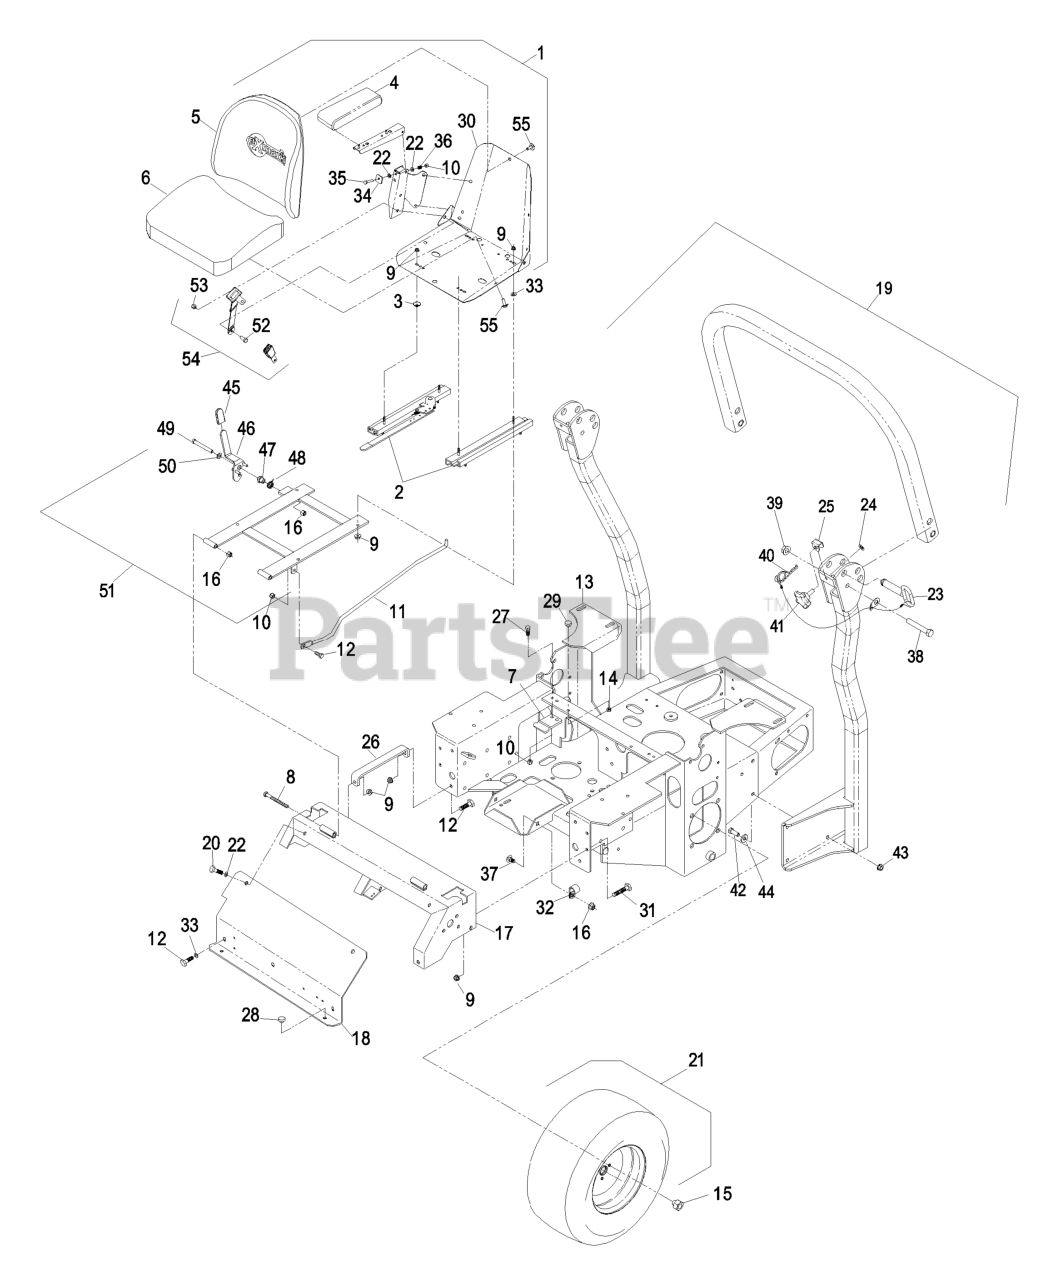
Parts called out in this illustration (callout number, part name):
1	KIT,SEAT W/ARMREST ADJ.
2	TRACK-SEAT
3	SPACER-TRACK
4	CUSHION,ARMREST RH
5	CUSHION,SEAT BACK
6	CUSHION,SEAT BOTTOM
7	CATCH-LATCH, SEAT
8	SCREW-HH
10	NUT-LOCK, NI
11	ROD-RETAINER, SEAT
12	SCREW-HH
15	NUT-LUG
16	NUT-LOCK, NI
17	ASM,CONSOLE WELDMENT W/DE
19	KIT, LAZER HP / CT 2 POST
20	SCREW-HH
21	ASM,WHEEL AND TIRE
22	WASHER-PLAIN
23	PIN-FOLD, ROPS
24	NUT-PUSH
27	SCREW-HH
30	FRAME-SEAT
31	SCREW-HH
32	CLIP-LOOM
33	WASHER-FLAT
34	TAB,ARMREST ADJUSTMENT
35	SCREW-HH
36	SPRING-TANK, FUEL
37	SCREW-CARR
38	SCREW-HH
40	HAIRPIN
42	SCREW-HH
43	NUT-HHF, WHIZ
44	Washer, Spring Disk 3/8
45	GRIP-LEVER
46	LATCH ASM
47	BUSHING-LATCH, SEAT
48	SPRING-TORSION
49	SCREW-HH
50	WASHER-FLAT
51	ASM,SEAT FRAME
52	SCREW-HH
53	NUT-LOCK
54	SEATBELT KIT
55	BOLT-SEAT
